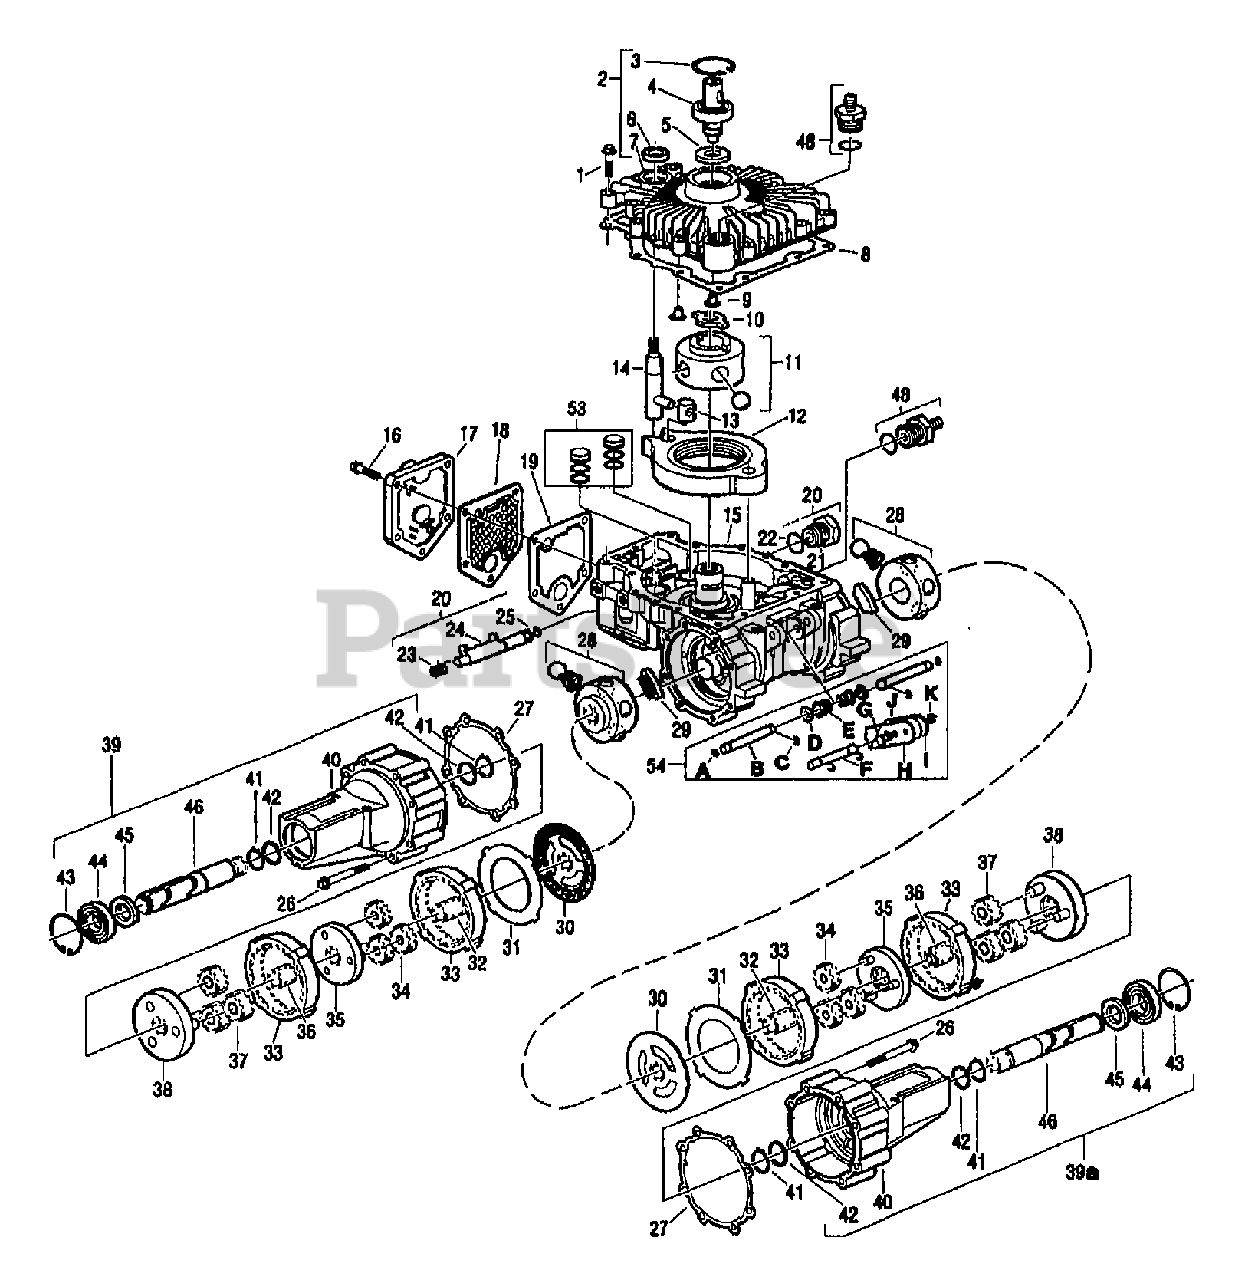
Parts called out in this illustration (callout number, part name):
4	SHAFT-INPUT
5	SEAL-OIL
6	SEAL-CONTROL SHAFT
18	FILTER-INTERNAL
19	GASKET-VALVE COVER
24	BRACKET
25	RING-O
44	BEARING
